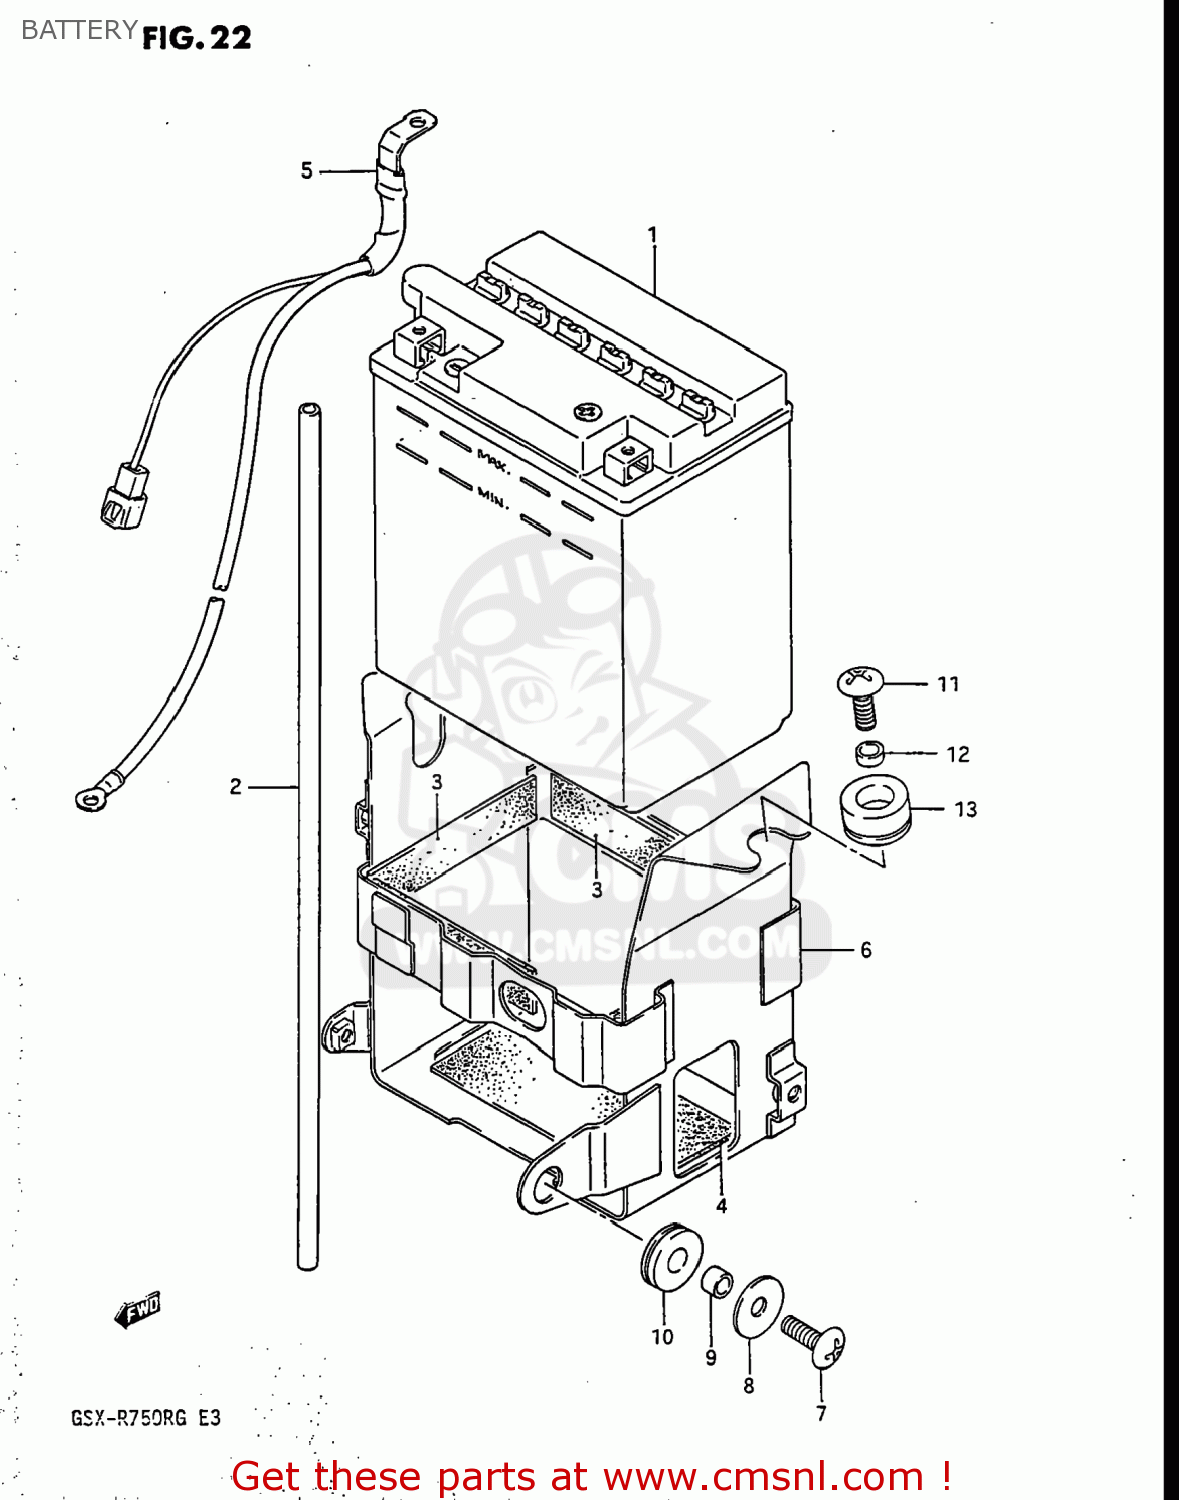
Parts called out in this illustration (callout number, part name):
1	BATTERY ASSY (12V)
2	HOSE,BATTERY EXHAUST
3	PROTECTOR,20X9
4	PROTECTOR(170X95X3.0)
5	WIRE,BATTERY MINUS LEAD
6	HOLDER,BATTERY
7	SCREW
8	WASHER (6.5X24X1.6)
9	SPACER
10	CUSHION
11	SCREW
12	SPACER
13	CUSHION,BATTERY HOLDER
